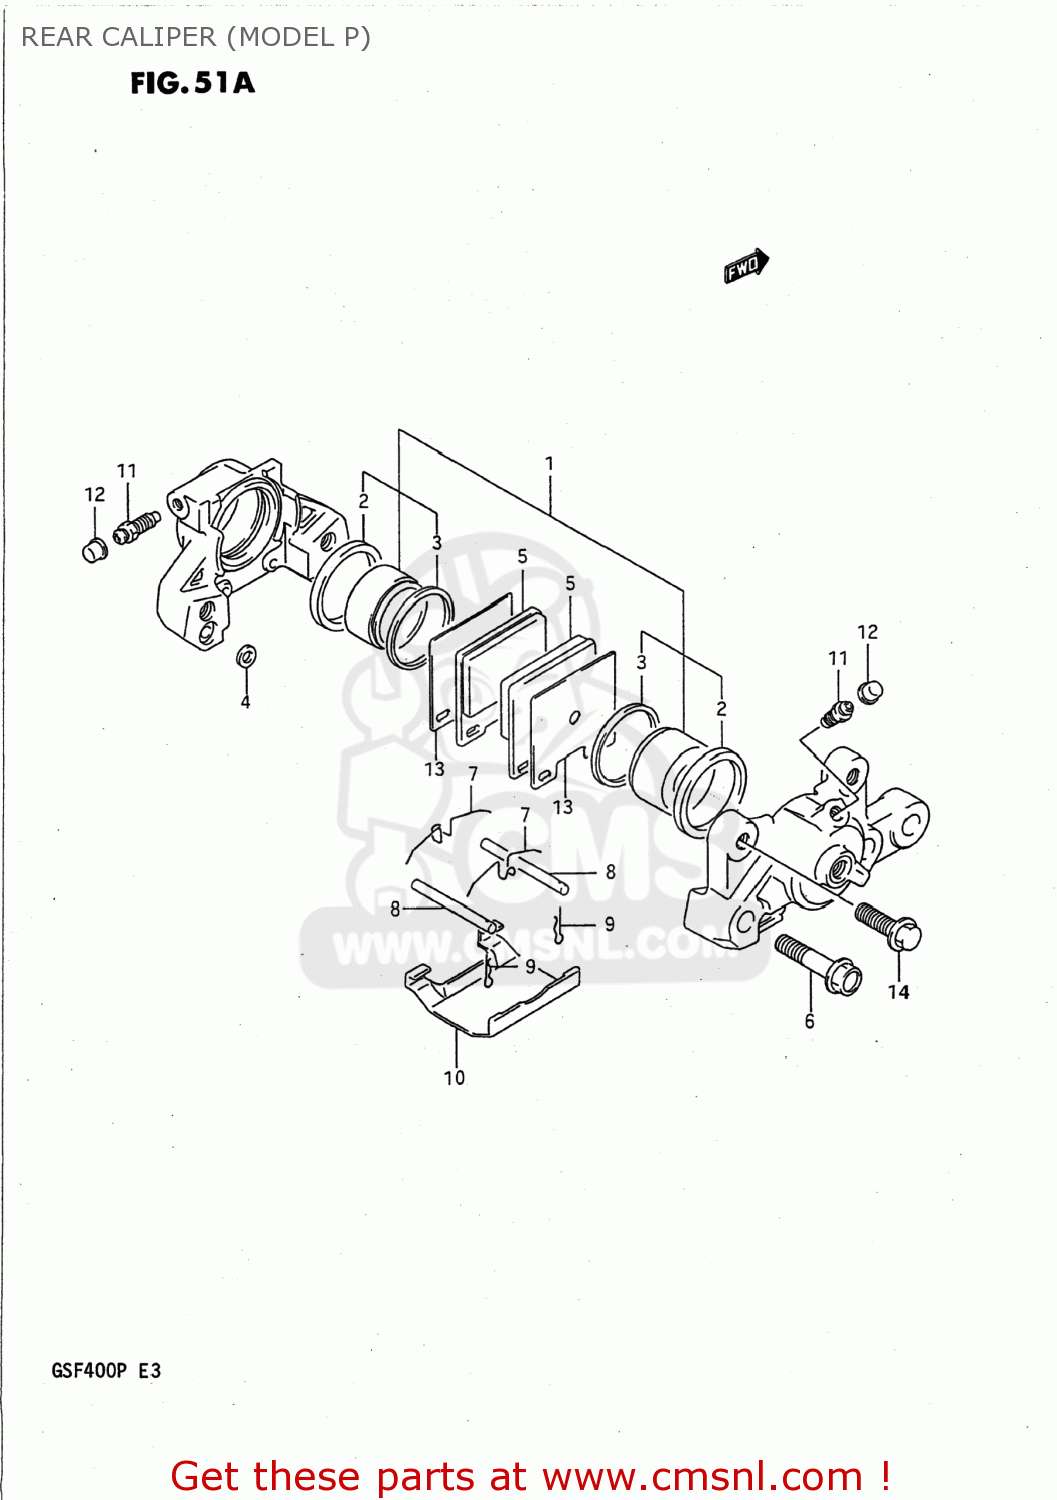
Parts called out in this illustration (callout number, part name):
1	PISTON SET
2	SEAL,PISTON
3	SEAL,WIPER
4	SEAL,JOINT
5	PAD,BRAKE
6	BOLT,HOUSING
7	SPRING
8	PIN,PAD
9	CLIP,PAD PIN
10	COVER
11	BLEEDER
12	CAP,BREATHER
13	SHIM,PAD
14	BOLT
